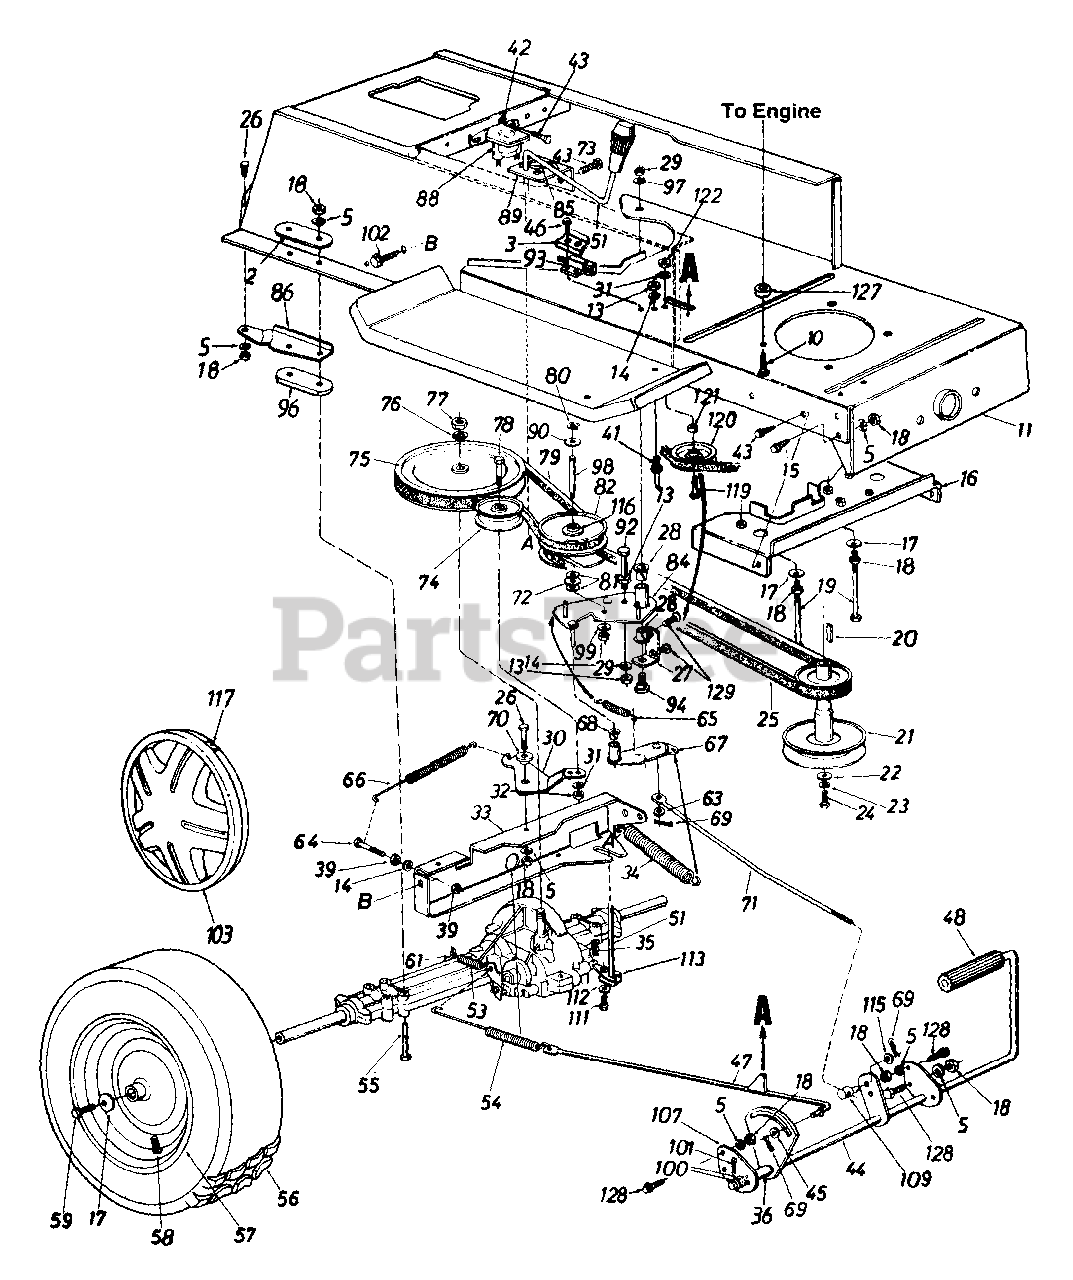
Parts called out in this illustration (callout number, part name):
3	Switch Plate
5	L-Wash. 5/16" I.D.
10	Hex L-Wash. Tap Scr. 3/8-16 x 1.5" Lg. (B&S)
11	Lower Frame Ass'y.
13	Hex Nut 1/4-20 Thd.
14	L-Wash. 1/4" I.D.
15	Hex TT-Tap Scr. 5/16-18 x.62"
16	Belt Guard Brkt. Ass'y.
17	Bell-Wash..345" I.D. x.88"
18	Hex Nut 5/16-18 Thd.
19	Hex Bolt 5/16-18 x 4.0"
20	Sq. Key 1/4" x 1/4" x 2.00"
21	Engine Pulley
22	Fl-Wash. 7/16" I.D. x 1.25"
23	L-Wash. 7/16" I.D.
24	Hex Bolt 7/16-20 x 1.50" Lg.
25	Variable-Speed Belt
26	Hex Bolt 5/16-18 x .75" Lg.
27	Bearing Shaft Bracket Ass'y.
28	Flanged Nyliner Brg. 5/8" I.D. x .88" Lg.
29	Hex Nut 3/8-24 Thd.
31	L-Wash. 3/8" I.D.
32	Hex Nut 3(8-24 Thd.
35	Inter. Cotter Pin
36	Spacer .63" I.D.
39	Hex Nut 1/4-28 Thd.
41	Belt Guard Pin
42	Ext. L-Wash. 1/4" I.D.
43	Hex Wash. Hd. S-Tap Scr. 1/4-20 x .50" Lg.
44	Clutch/Brake Pedal Ass'y.
45	Fl-Wash.
46	Truss Mach. Scr. B-Tap Scr. 010 x .5" Lg.
47	Brake Rod Ass'y.
48	Foot Pad
51	Shift Lever Ass'y.
53	Ext. Spring .38" O.D. x 2.5"
54	Ext. Spring .59" O.D. x 7.08"
55	Hex Bolt 5/16-18 x 3.5" Lg.
57	Wheel Rim Only 18" x 9.50"
58	Air Valve
59	Hex Bolt 5/16-24 x .75" Lg.
63	Fl-Wash..34" I.D. x .68" O.D.
64	Hex Bolt 1/4-28 x 1.25" Lg.
65	Ext. Spring
66	Ext. Spring .62" O.D. x 6,12"
68	Flanged Bearing
69	Cotter Pin 3/32" Dia.
70	Shoulder Spacer .27" Lg.
71	Speed Control Link
72	Truss Bearing .56 Dia. x 1.25"
73	Shift Knob
74	Fl-Idler Pulley 3.25" x .75"
75	"V" Pulley
76	Bell-Wash..56" I.D. x 1.125"
77	Hex Jam Nut 5/16-18 Thd.
78	Hex Bolt 3/8-24 x 1.75" Lg.
79	Variable Speed Belt
80	Snap Ring .56" Dia.
81	Fl-Wash.
82	Variable Speed Pulley Ass'y. 5" O.D.
84	Variable Speed Brkt. Ass'y.
85	Comp. Spring - Clip
90	Teflon Washer .565" I.D.
92	Hex Bolt 1/4-20 x 3.5" Lg.
93	Safety Switch (Clutch)
94	Shld. Bolt 3/8-24 x 3.12" Lg.
96	Transaxle Spacer
97	Bell-Wash..38" I.D. x.88"
98	Shaft .56" Dia. x 3.875" Lg.
99	Bell-Wash..39" I.D. x 1.12"
100	Fl-Wash..64" I.D. x .94"
101	Cotter Pin 1/8" Dia. x 1.25"
102	Hex Wash. Hd. Scr. 5/16-18 x .62" Lg.
103	Hub Cap (Gray)
109	Ferrule
111	Hex Bolt 1/4-28 x .50" Lg.
112	Bell-Wash..265" I.D. x .75"
113	Shift Lever Link Ass'y.
115	Fl-Wash..385" I.D. x .62"
116	Needle Brgs.
117	Spring Clip
119	Hex Bolt 3/8-16 x 1.25" Lg.
120	Fl-Idler w/Flanges 2.75" O.D.
121	Fl-Wash..39" I.D. x 1.12" O.D.
122	Hex Nut 3/8-16 Thd.
127	Spacer 5/16" I.D.
128	Hex Wash. TT-Tap Scr. 5/16-18 x .75" Lg.
129	Hex Wash. AB-Tap Scr. 5/16-18 x .75" Lg.
